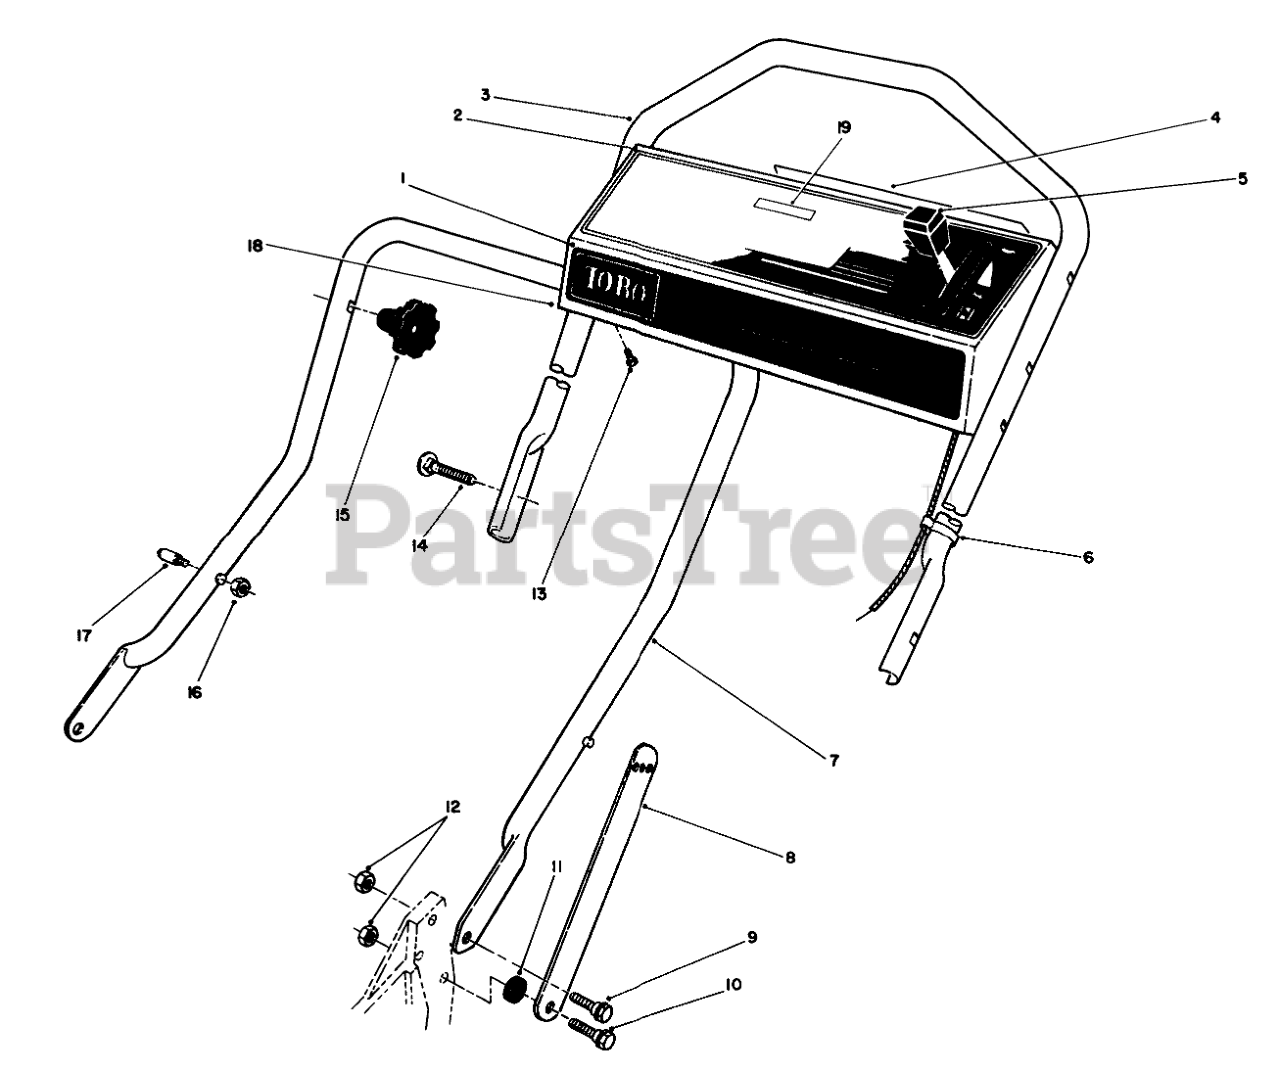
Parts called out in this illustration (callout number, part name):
1	DECAL - TORO PANEL
2	Decal-Instruction
3	Handle-Upper
4	DECAL - PANEL, REAR
5	THROTTLE CONT-SERVICE
6	BOWDEN CLIP
7	Lower Handle Assembly (Incl. Ref. #16-17)
8	Handle Latch
9	SCREW-SHOULDER
10	SCREW-SHOULDER
11	SPACER
12	NUT-LOCK, NI
13	SCREW-HWHTF
14	5/16-18 X 2 HNDLE SCREW
16	NUT-LOCK, NI
17	HANDLE PIN
18	Panel-Control (Incl. Ref. #1, 2, & 4)
19	Decal-Made In Canada
